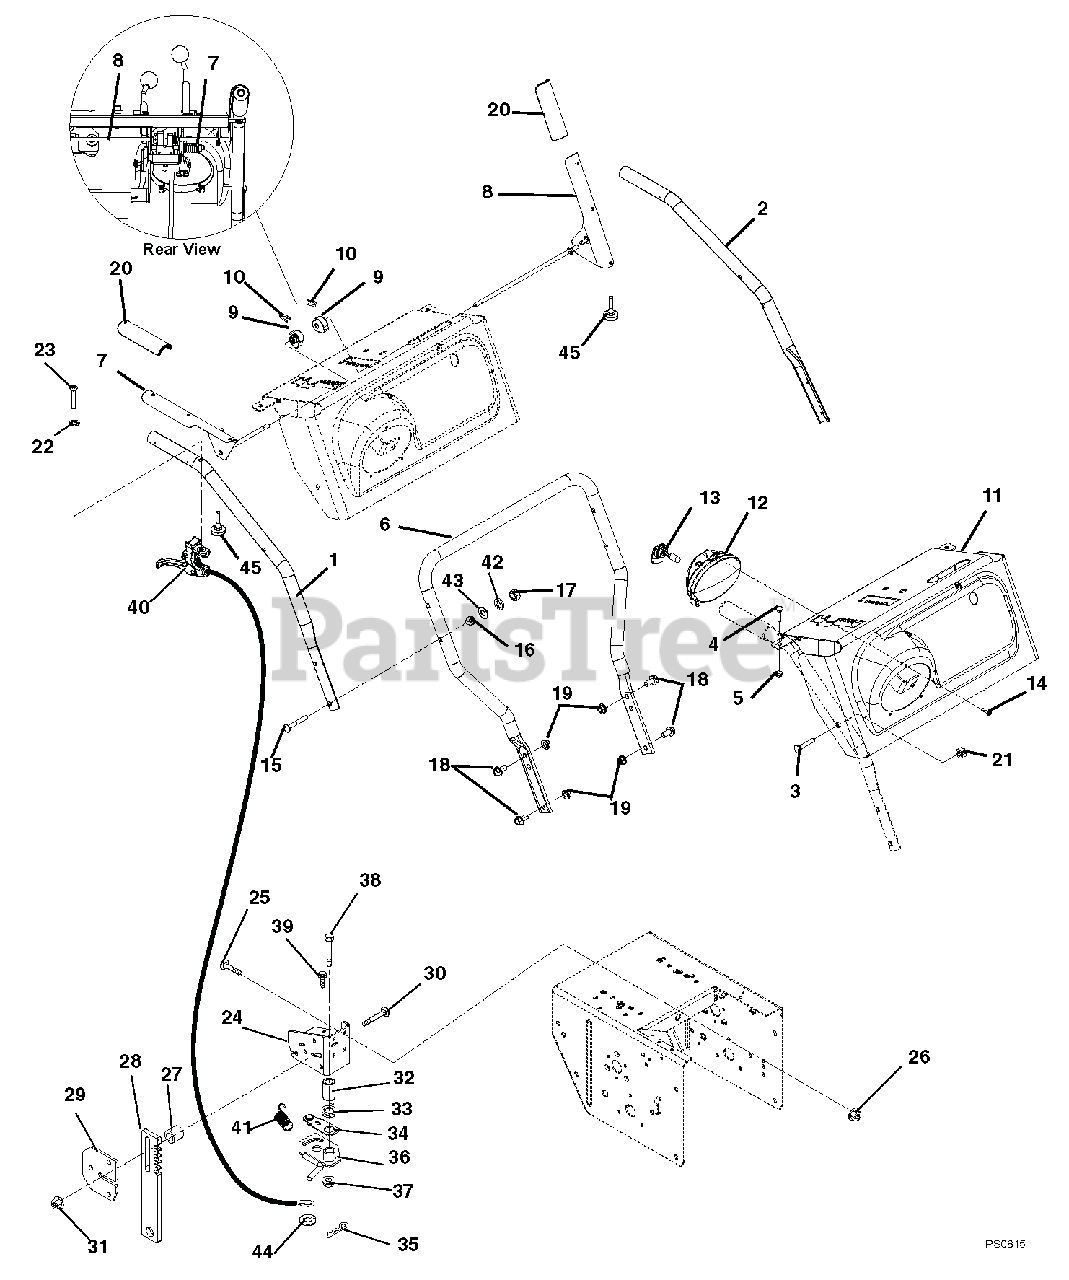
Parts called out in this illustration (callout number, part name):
1	HANDLEBAR, UPPER RH-W/HW
2	HANDLEBAR, UPPER LH-W/HW
3	@BLT-RDHDSQNK .31-18X1.75 G5YZ
4	BLT-RDHDXLSQNK.25-20X1.25 G5ZC
5	@NUT-LK-TOP-FLG .25-20 YWZC
6	HANDLEBAR, LOWER
7	LEVER, RH-ATTACHMENT
8	LEVER, LH-TRACTION
9	CAM, INTERLOCK NYLON, LG DASH
10	PIN, SPRING CLIP
11	PANEL-W/CONTROL HW DECAL
11	PANEL-W/CONTROL 12V DECAL
11	CONTROL PANEL W/DECAL - TRACK
11	PANEL-W/CONTROL 12VTRACK DECAL
11	PANEL-W/CONTROL BRUSH DECAL
12	LIGHT, HALOGEN ASSY.
13	BULB, LIGHT-HALOGEN 20W
14	SCR-TAP 10-16X.75 HI-LO PPH
15	@BLT-RDHDSQNK .31-18X2.25 G5YZ
16	SPACER, HANDLEBAR
17	@NUT-LK-NYL .312-18 YWZC
18	BLT-SERHFWH .38-16X.75 YWZC
19	@NUT-LK-TOP-FLG .38-16 YWZC
20	GRIP, CLUTCH LEVER, LH AND RH
21	@NUT-LK-CTR .31-18 YWZC
22	WSHR-LK-INT .250 TH TYA
23	SCR-MCH .25-20X1.50 OVAL HD
24	BRACKET, HEIGHT ADJUSTER-PRO
25	@BLT-RDHDSQNK .25-20X.75 G5YZ
26	@NUT-LK-TOP-FLG .25-20 YWZC
27	SPACER .50 X .32 X .42
28	STOP, HEIGHT ADJUSTER-PRO
29	PLATE, HEIGHT ADJUSTER
30	@BLT-RHDSHSQNK.31-18X1.25 G5YZ
31	@NUT-LK-TOP-FLG .31-18 YWZC
32	BSHG-SLV .385X.500X1.045
33	SG-TORS .067X.88
34	ARM, OVERTRAVEL
35	PIN-HAIR INT .06X.18X.77
36	LOCK, HEIGHT ADJUSTER
37	NUT-LK-CTR-FLG .38-16 YWZC
38	@BLT-HEX .38-16X1.75 GR5 YWZC
39	SCR-TAP .25-20X.50 HWH TR YWZ
40	CABLE, TRACK REMOTE
41	SPRING-EXT .047 X .438 X 1.85
42	WSHR-LK .312X.097 HVY YWZC
43	@WSHR-FL-STL.38X.875X.083 YWZC
44	@WSHR-FL-STL.281X.62X.065 YWZC
45	BUMPER, RUBBER - PULL MOUNT
